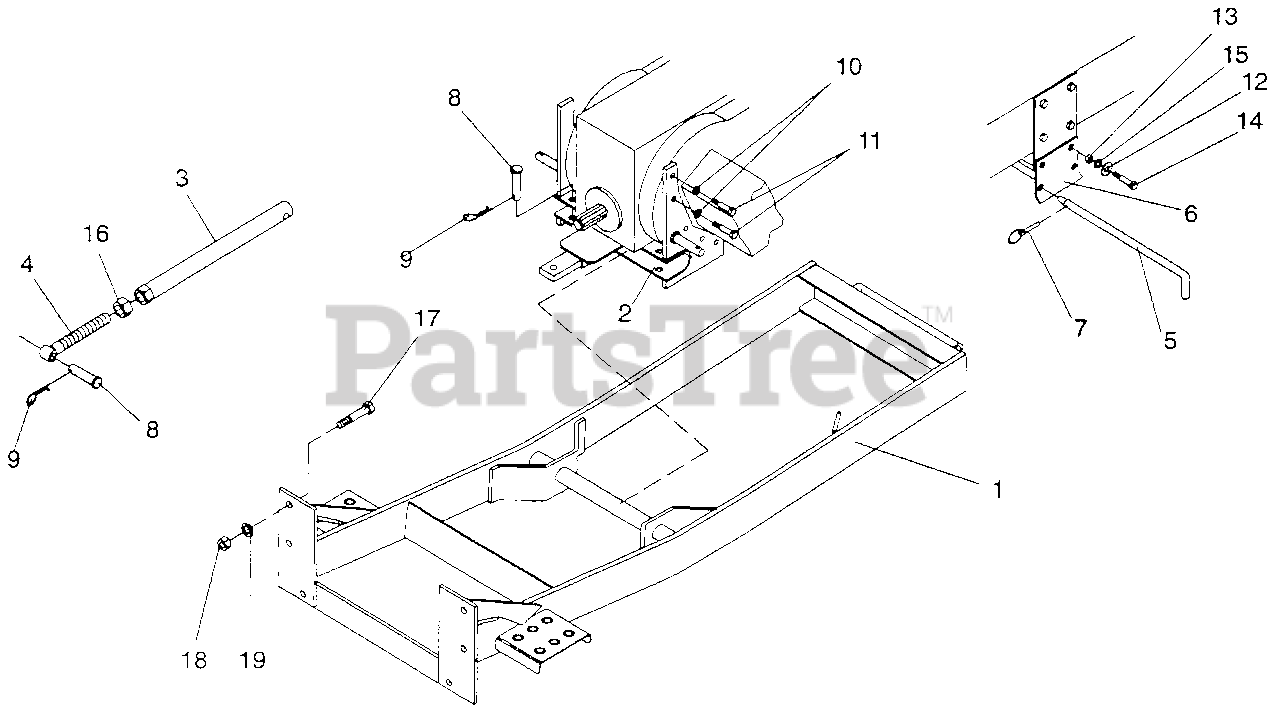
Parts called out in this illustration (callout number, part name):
1	Backhoe sub-frame 24.4 x 74 assembly
2	Rear mounting bracket assembly
3	Outer link assembly, 19.5
4	Inner top link assembly
5	3/4 x 17.75 Lock pin
6	Front mounting bracket assembly
7	1/4 x 1-3/4 Klik pin
8	3/4 x 3-1/4 Clevis pin
9	1/8 Hairpin cotter
10	9/16 Standard lockwasher
11	10 mm x 1.5P x 85 mm Hex head cap screw
12	1/2 Washer
13	1/2 Locknut
14	1/2 NC x 1-1/2 Hex head cap screw
15	1/2 Lockwasher
16	1 Hex nut
17	3/4 NC x 2 Hex head cap screw
18	3/4 NC Nut
19	3/4 Lockwasher
